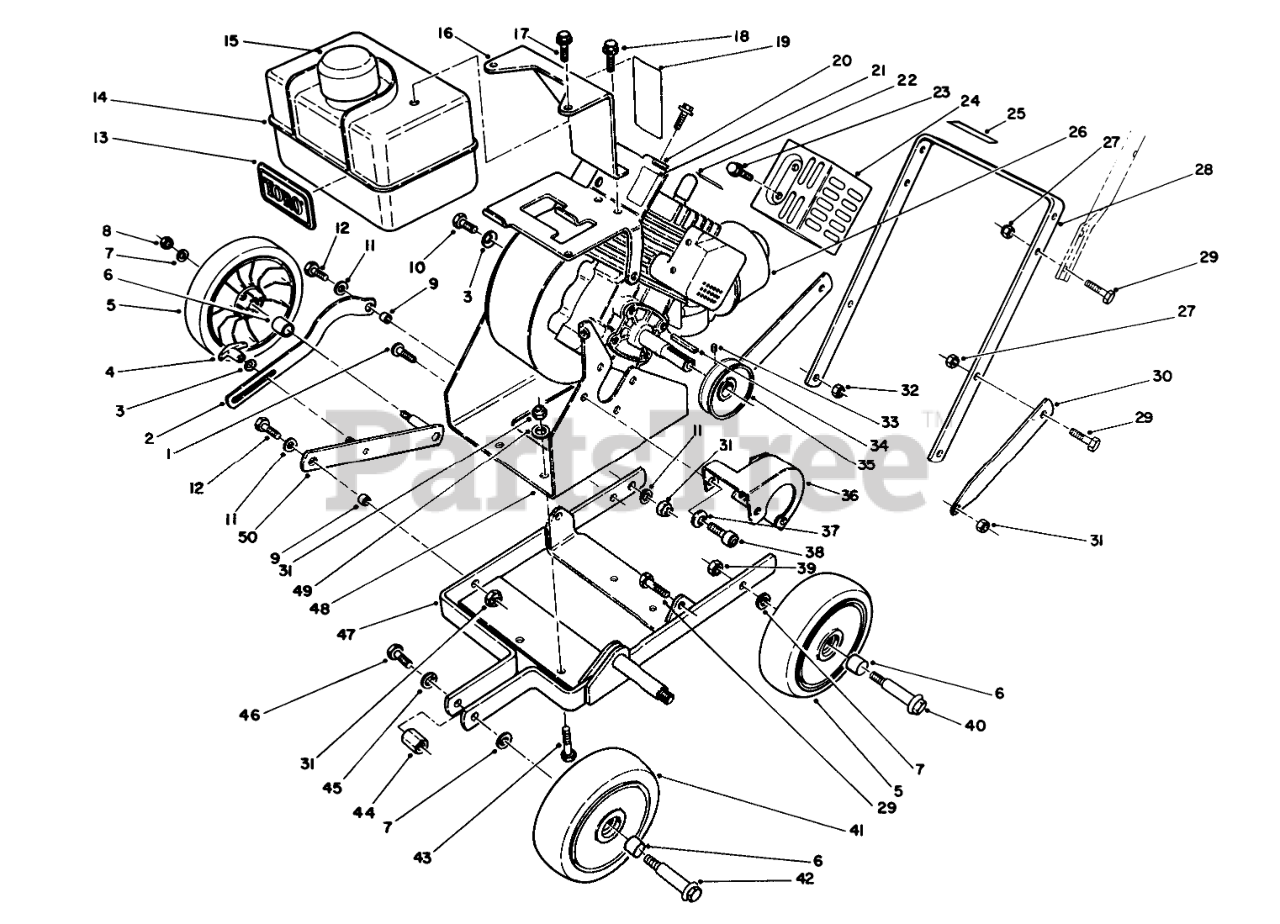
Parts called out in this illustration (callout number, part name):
1	3/8-24 X 1.00HEX BU. HD
2	AXLE LINK
3	BELLEVILLE SPRING WASHE
5	Wheel & Tire Assembly (Incl. Ref. #6)
6	BUSHING
7	WASHER
8	NUT-LOCK
9	WHEEL MT BUSHING
10	SCREW-HH
11	WASHER-FLAT
12	SCREW-HH
13	TORO LOGO PLT
15	Cap-Fuel
16	TANK STRAP
17	Screw-Cap Hex. Hd.
18	SCREW-HWHTF
19	Decal-Fuel Mixture
20	TANK BASE
21	DECAL-SURFACE, HOT
22	DECAL-IGNITION
23	Screw-Cap Hex. Hd.
24	MUFFLER COVER
25	DECAL-WARNING
26	Engine-2 Cycle
27	NUT-LOCK, NI
28	LOWER HANDLE
29	SCREW-HH
30	SUPPORT HANDLE
31	NUT-LOCK, NI
32	NUT-LOCK
33	SCREW-SET
34	KEY-SQUARE
35	2HP PULLEY
36	GUARD-ENGINE PULLEY
37	WASHER-BELLEVILLE
38	SCREW-HSH
39	NUT-HEX
40	WHEEL BOLT
41	Wheel & Tire Assembly (Incl. Ref. #6)
42	BOLT-WHEEL
43	SCREW-HH
44	HEX SPACER
45	WASHER-LOCK
46	SCREW-HH
47	Frame-Edger
48	ENGINE FRAME
49	WASHER-PLAIN
50	WHEEL MOUNT WA
